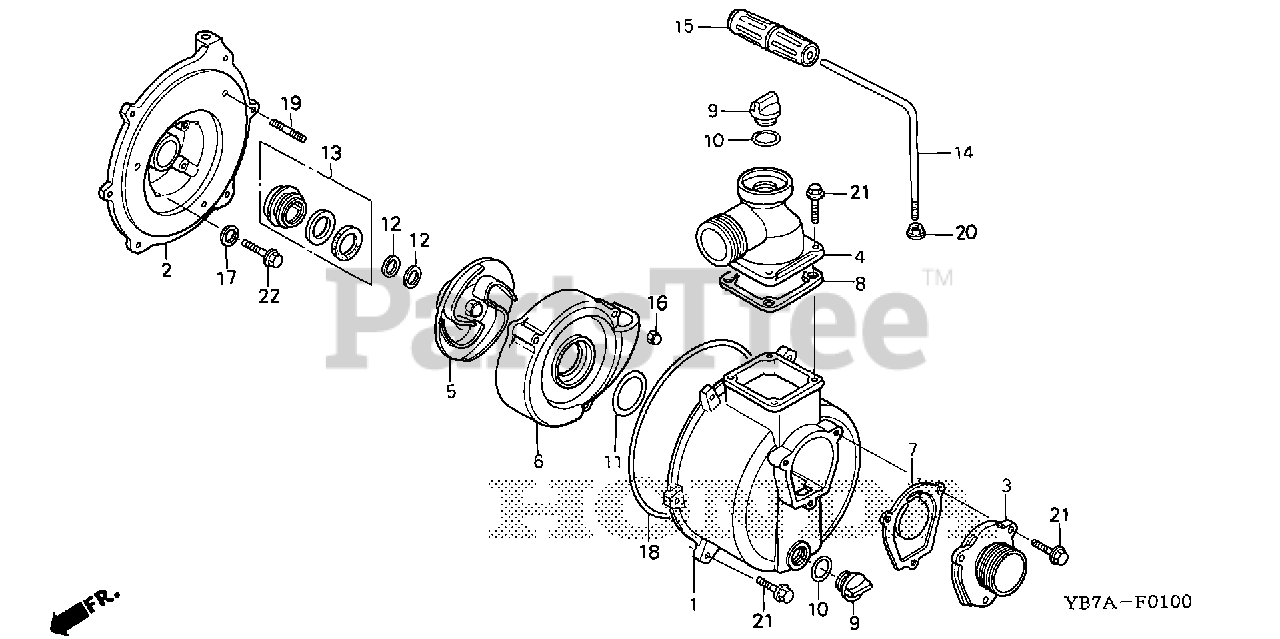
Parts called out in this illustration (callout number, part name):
2	COVER, CASING
3	PIPE, INLET
4	PIPE, OUTLET
5	IMPELLER
6	CASE, VOLUTE
7	VALVE, IN.
8	GASKET, OUTLET
9	CAP, FILLER (ENGINE NO.)
10	RING, SEAL (B)
11	O-RING (49X5.7) (NOK)
12	SHIM, ADJUSTER
13	SEAL, MECHANICAL
15	GRIP, HANDLE
16	NUT, CAP (6MM)
17	WASHER, SEALING (8MM)
18	O-RING (217.5X3.5) (ARAI)
19	BOLT, STUD (6X35)
20	NUT, HEX. (14MM)
21	BOLT, FLANGE (8X25)
22	BOLT, FLANGE (8X28)
